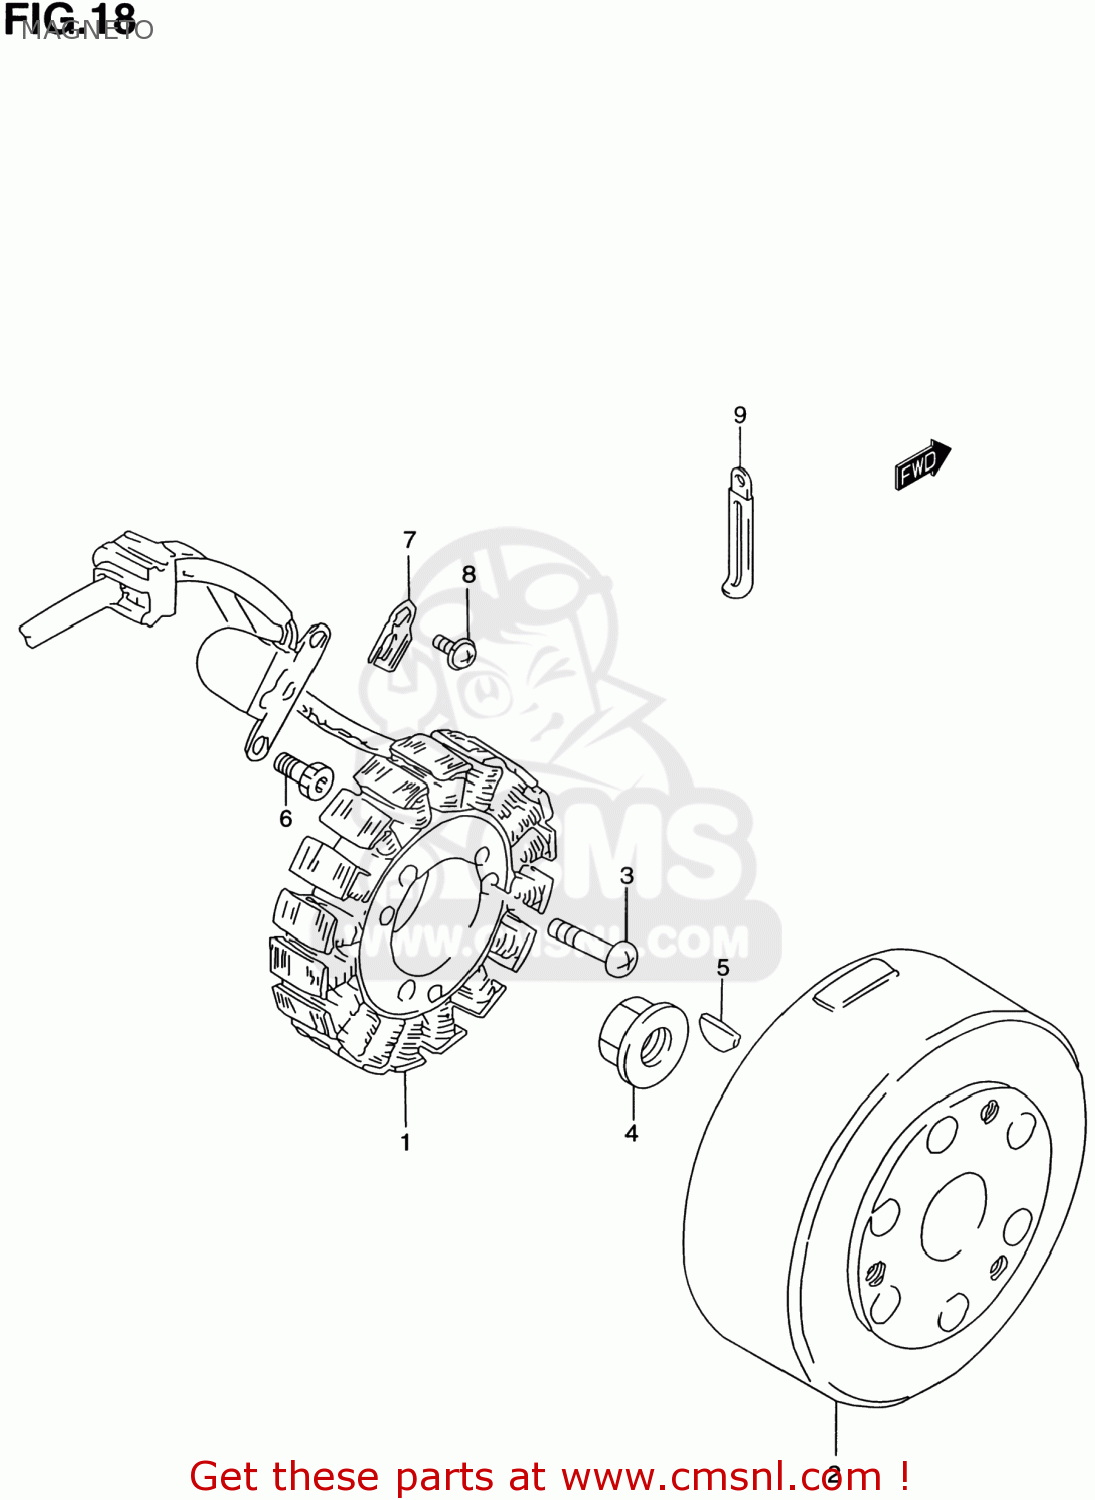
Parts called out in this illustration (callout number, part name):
1	STARTER ASSY
2	ROTOR ASSY
3	SCREW
4	NUT,GENERATOR ROTOR
5	KEY
6	BOLT
7	CLAMP,GENERATOR LEAD WIRE
8	SCREW
